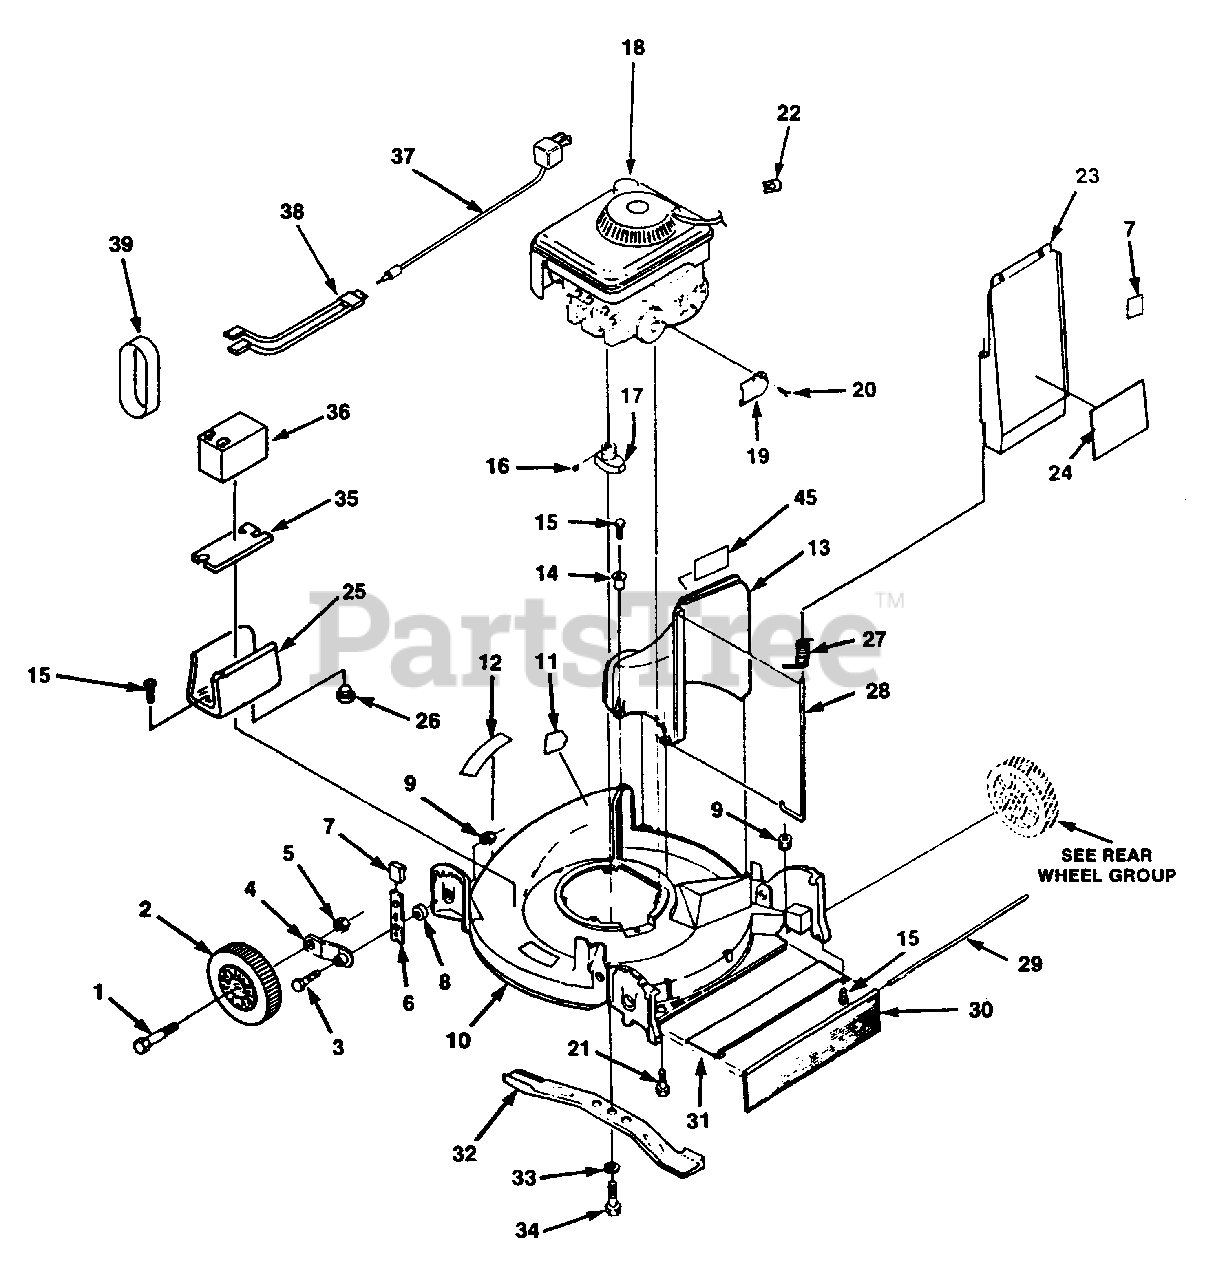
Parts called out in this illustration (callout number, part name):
1	BOLT & NUT ASSY. (Incl. Ref. No. 5)
2	WHEEL & TIRE
3	BOLT, Hex Hd., 5/16-18
4	ARM, Wheel Hgt. Adj.
5	NUT, Hex, 3/8-24
6	SPRING, Index
7	KNOB, Indexing Spring
8	SPACER, Index Spring
9	NUT, Flange, 5/16-18
10	DECK, 21" (Incl. Ref. No. 11 and 12)
11	DECAL, 21"
12	DECAL, Warning
13	CHUTE, Discharge (Incl. #14)
14	EYELET, Simpson
15	SCREW, Hex Hd., 1 /4-20 x 3/4
16	KEY, 5/8 x 5/32
17	ADAPTER, Blade
19	DEFLECTOR, Muffler
20	SCREW, Hex Hd., 8-32 x 3/8
21	SCREW, 3/8-16 x 1-1/2
22	STOP, Rope
23	DOOR, Chute (Incl. #24)
24	DECAL, Door
25	HOLDER, Battery
26	BUMPER
27	SPRING, Door
28	PIN, Hinge
29	ROD, Drag Flap
30	FLAP, Drag
31	COVER, Rear
33	WASHER, Lock 7/16
34	BOLT, Shoulder
35	PAD, Battery
36	BATTERY, 12 Volt
37	CHARGER, Battery
38	LEAD, Battery
39	STRAP, Rubber
